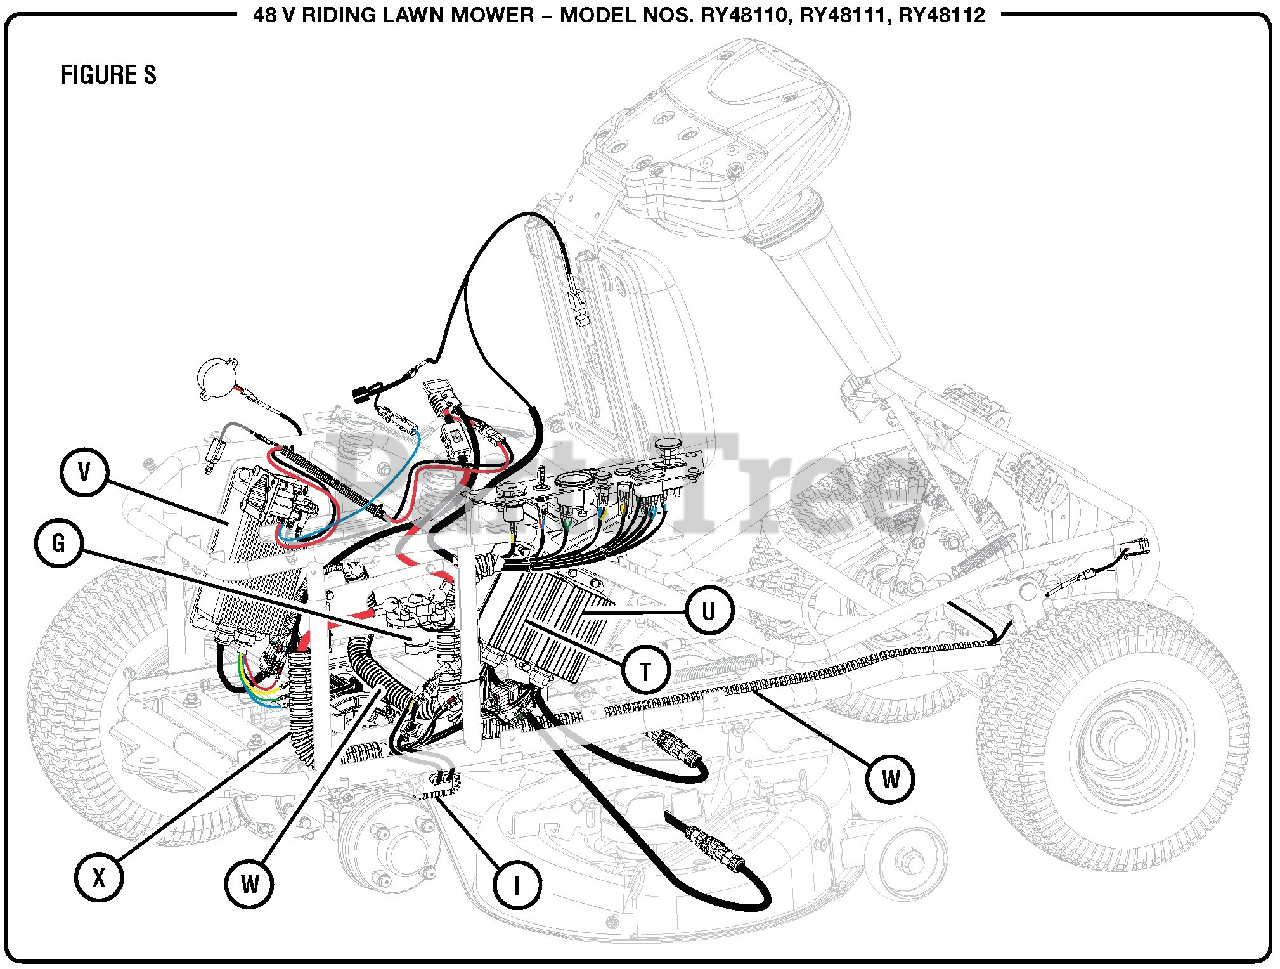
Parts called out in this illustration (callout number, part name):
1	12 Volt Power Converter (I)
2	Master Deck Motor Controller (T)
3	Slave Deck Motor Controller (U)
4	Drive Motor Controller (V)
5	Main Wiring Harness (W)
6	Sub Wiring Harness (X)
7	Main Relay (G)
